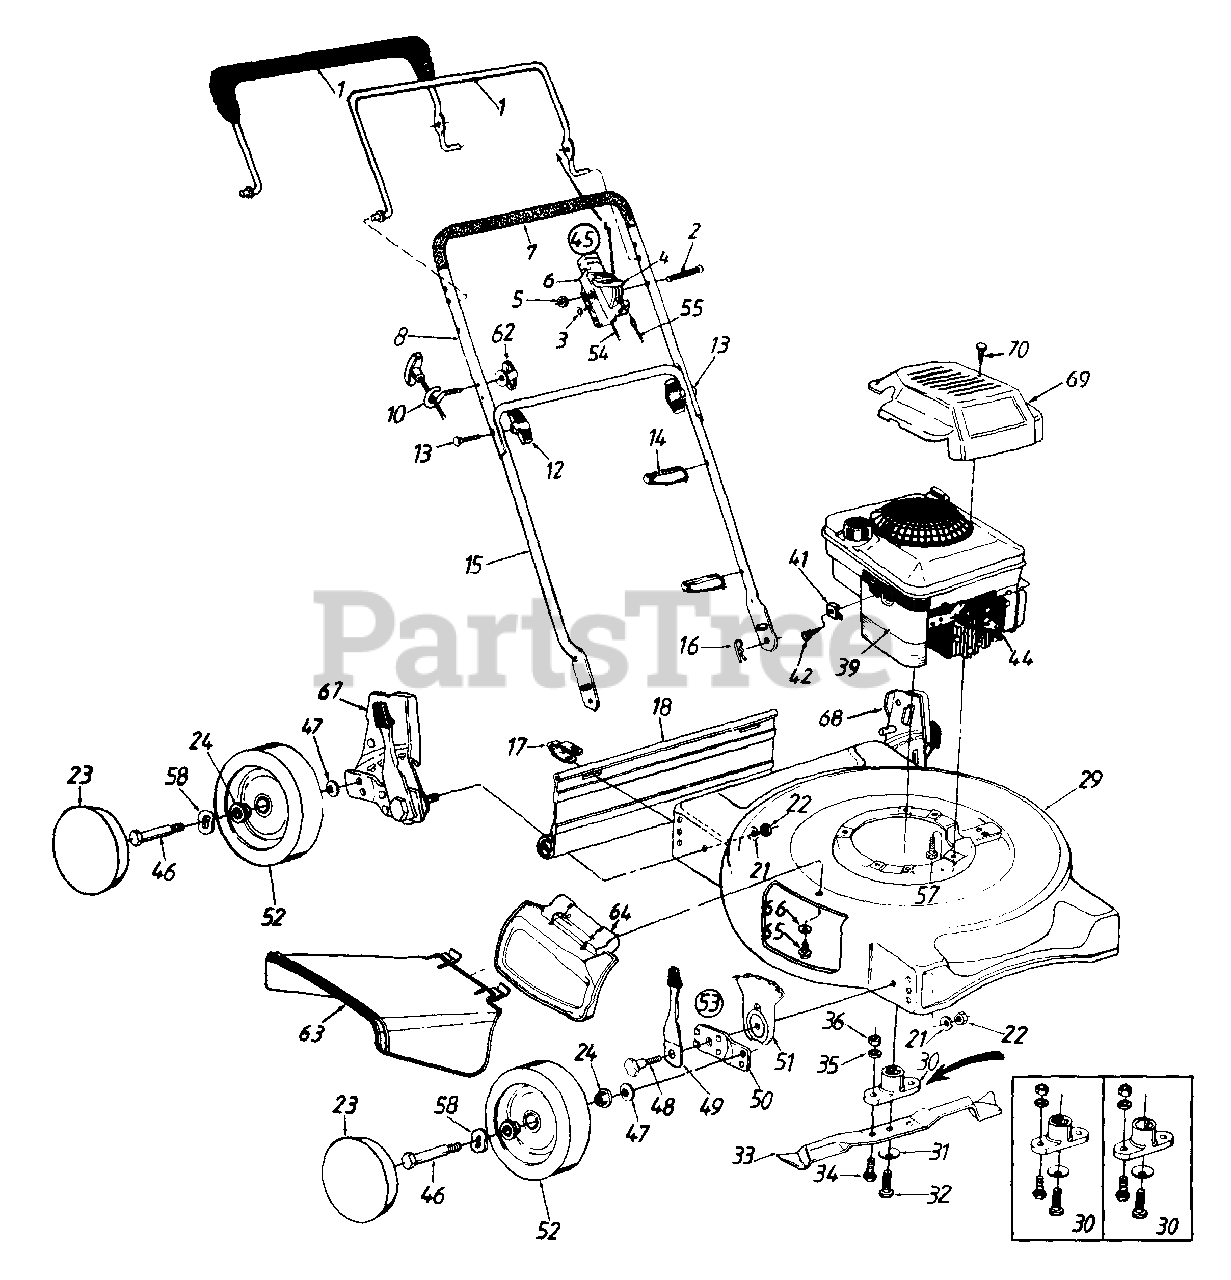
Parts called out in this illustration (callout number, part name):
1	Control Handle Ass'y.
2	Oval C-Sunk Scr.
3	Spr. Wash .66" I.D.
4	Throttle Lever
5	Hex L-Nut 1/4-20 Thd.
6	Throttle Body
7	Grip
12	Hand Knob
13	Curved Hd. Bolt 5/16-18 x 2" Lg.
14	Cable Tie
16	Hairpin Cotter
17	Hinge Clip
18	Rear Flap
21	Bell-Wash .39" I.D. x 1.38"
22	Hex Nut 3/8-16 Thd.
23	Hub Cap
24	Bearing
29	20" Deck Ass'y.
30	Blade Adapter Kit (Keyed)
31	Bell-Wash .39" I.D.
32	Hex Bolt 3/8-24 x 1.5" Lg.
33	20" Mulching Blade
34	Hex Bolt 3/8-24 x 1" Lg.
35	L-Wash. 3/8" I.D.
36	Hex Nut 3/8-24 Thd.
39	Engine
41	Cable Clamp (B&S)
42	Hex Self-Tap Scr. #10-32 x .62" (B&S)
44	Spark Plug Boot
45	Throttle Box Comp.
46	Axle Bolt
47	Bell-Wash .400" I.D. x.88"
48	Shld. Bolt .50" Dia. x .357"
49	Spring Lever Ass'y. w/Knob
51	Height Adj. Plate
52	Wheel Ass'y. Comp.
53	Height Adj. Ass'y. Comp.- R.F.
54	Throttle Cable - 51" (B&S)
55	Control Cable - 39" (B&S)
57	Hex L-Wash. Hd. Scr. 3/8-16 x 1.0" Lg.
58	Wave Washer .51" I.D.
62	Handle Knob 1/4-20 Thd.
63	Chute Deflector
64	Mulching Plug
65	Hex Wash. Hd. TT-Tap Scr. 1/4-20 x .5" Lg.
66	Bell-Wash. 1/4" I.D.
69	XTE Engine Shroud (Black)
70	Hi-Lo Scr. #10 x 1.25" Lg.
